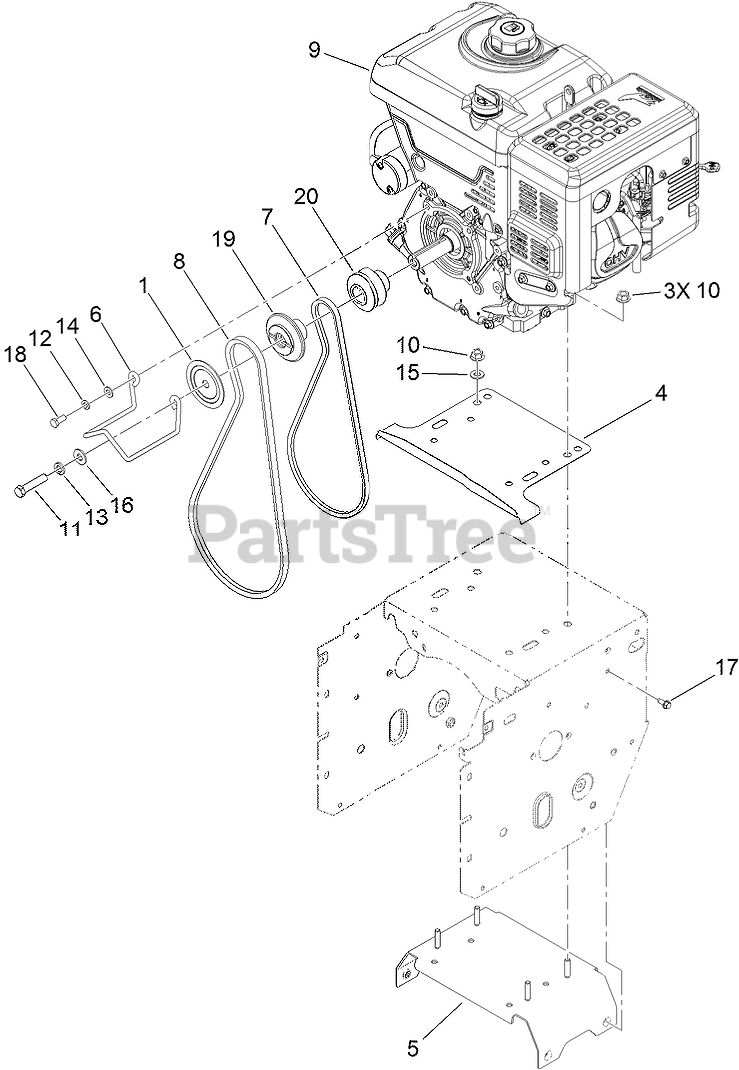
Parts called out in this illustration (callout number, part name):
1	SHEAVE-HALF, IMPELLER
4	SHIELD-DRIVE
5	FRAME BRACE ASM
6	GUIDE-BELT
7	BELT-V
8	BELT-V
9	ENGINE-180FDS-1
10	NUT-FLANGE
11	SCREW-HH
12	WASHER-LOCK
13	WASHER-LOCK
14	WASHER-PLAIN
15	WASHER-FLAT
16	WASHER-FLAT
17	SCREW-HWH
18	SCREW-HH
19	PULLEY-ENGINE, IMPELLER
20	PULLEY-TRACTION
